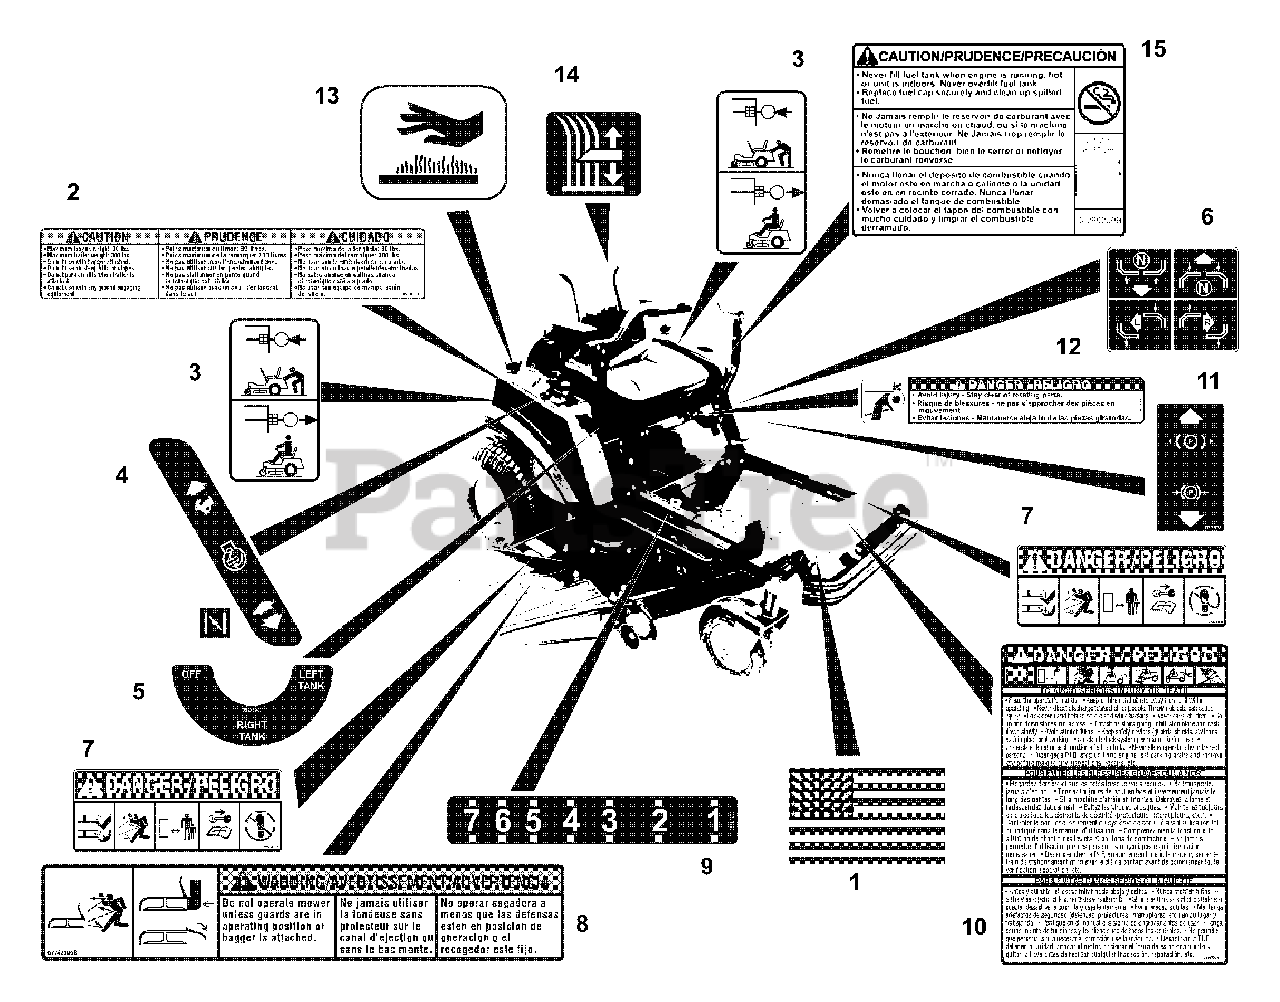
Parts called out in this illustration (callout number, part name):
1	Decal, American Flag
2	Decal, Trailer Hitch
3	Decal, Transmission Disconnect
4	Decal, Control
5	Decal, Fuel Valve
6	Decal, Instructional Steering
7	Decal, Mower Pan Head Danger
8	Decal, Warning
9	Decal, Cut Height Zoom
10	Decal, Bilingual Danger
11	Decal, Parking Brake Lever
12	Decal, Danger
13	Decal, Hot Surface
14	Decal, Cut Height
15	Decal, Fuel Warning
